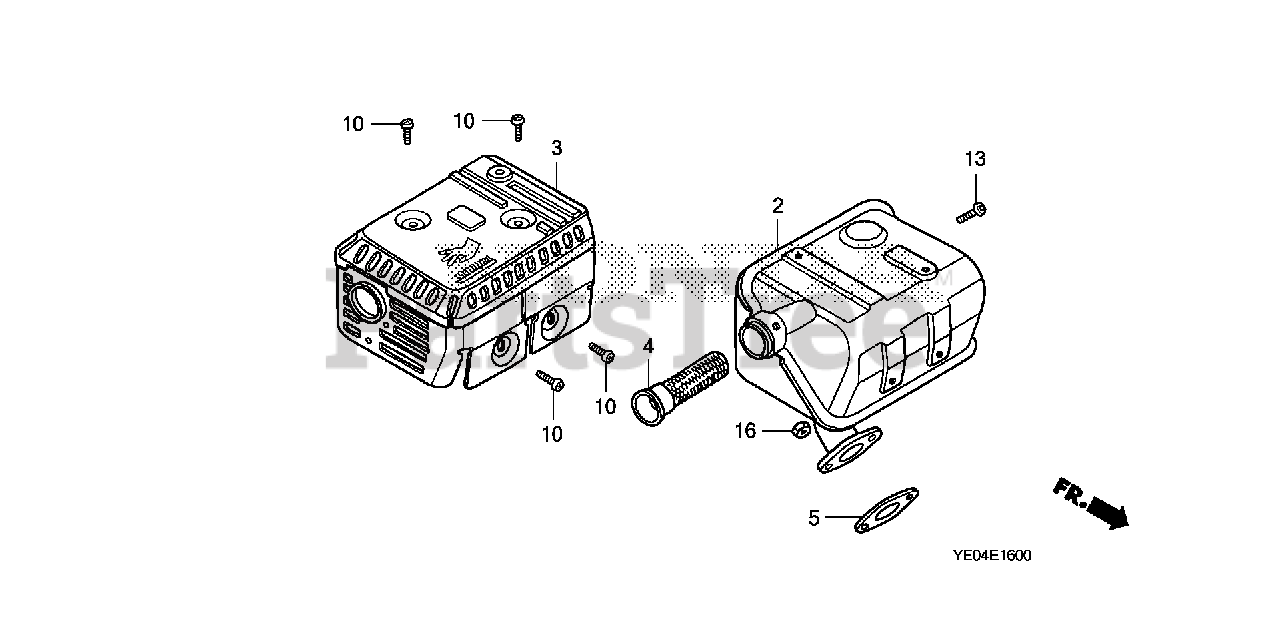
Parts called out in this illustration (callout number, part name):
2	MUFFLER (STD)
2	MUFFLER (ARRESTER)
3	PROTECTOR, MUFFLER (STD) (BLACK)
4	ARRESTER, SPARK
5	GASKET, MUFFLER
10	SCREW, TAPPING (5X8)
13	SCREW, TAPPING (4X6)
16	NUT, HEX. (8MM)
